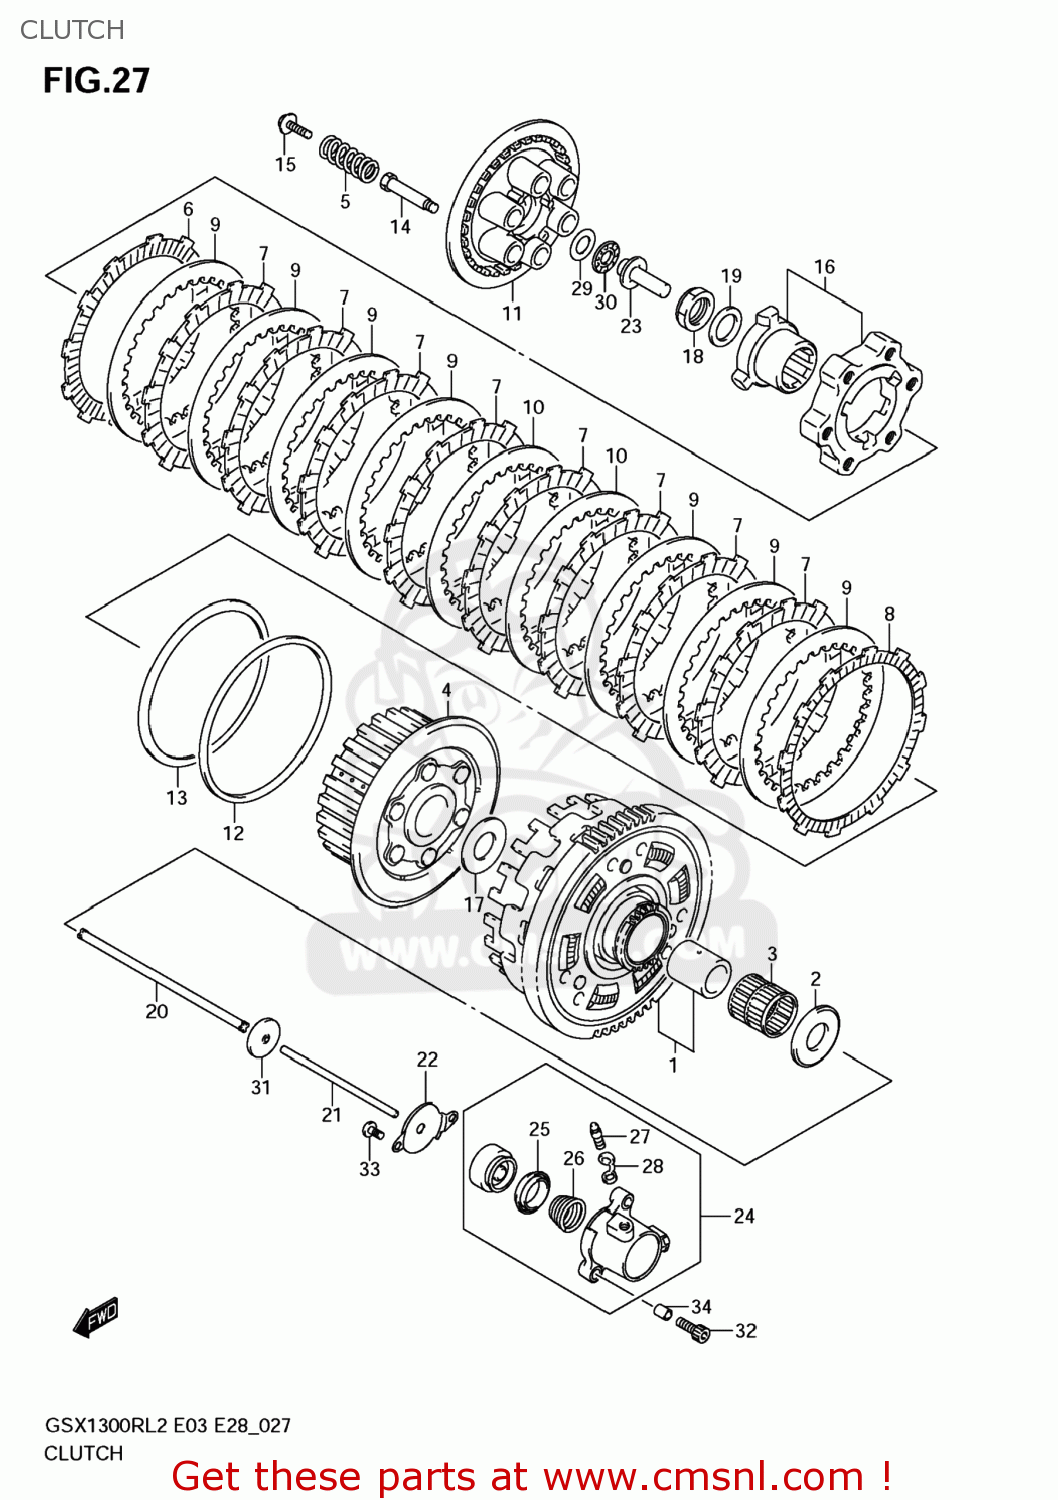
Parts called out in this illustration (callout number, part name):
1	GEAR ASSY,PRI DRIVEN
2	WASHER(25X54X2.4)
3	BEARING(35X40X39.8)
4	HUB,CLUTCH SLEEVE
5	SPRING,CLUTCH
6	PLATE,CLUTCH DRIVE NO.2 (NAS)
7	PLATE,CLUTCH DRIVE NO.1 (NAS)
8	PLATE,CLUTCH DRIVE NO.3 (NAS)
9	PLATE,CLUTCH DRIVEN NO.1(T:2.0 (NAS)
10	PLATE,CLUTCH DRIVEN NO.2(T:2.3 (NAS)
11	DISC,CLUTCH PRESSURE
12	SEAT,WAVE WASHER
13	WASHER,CLUTCH PLATE WAVE
14	BOLT,CLUTCH SP
15	BOLT,CLUTCH SPRING
16	CAM SET,CLUTCH
17	WASHER(25X50X2.5)
18	NUT
19	WASHER
20	ROD,CLUTCH
21	ROD,CLUTCH PUSH,L
22	COVER,CLUTCH RELEASE CYLINDER
23	PIECE,CLUTCH PUSH
24	CYLINDER,CLUTCH RELEASE
25	CUP
26	SPRING
27	BLEEDER
28	CAP,BLEEDER
29	WASHER(15.5X28X1)
30	BEARING(15X28X2)
31	SEAL,OIL(6X34X5.5)
32	BOLT
33	SCREW
34	PIN
